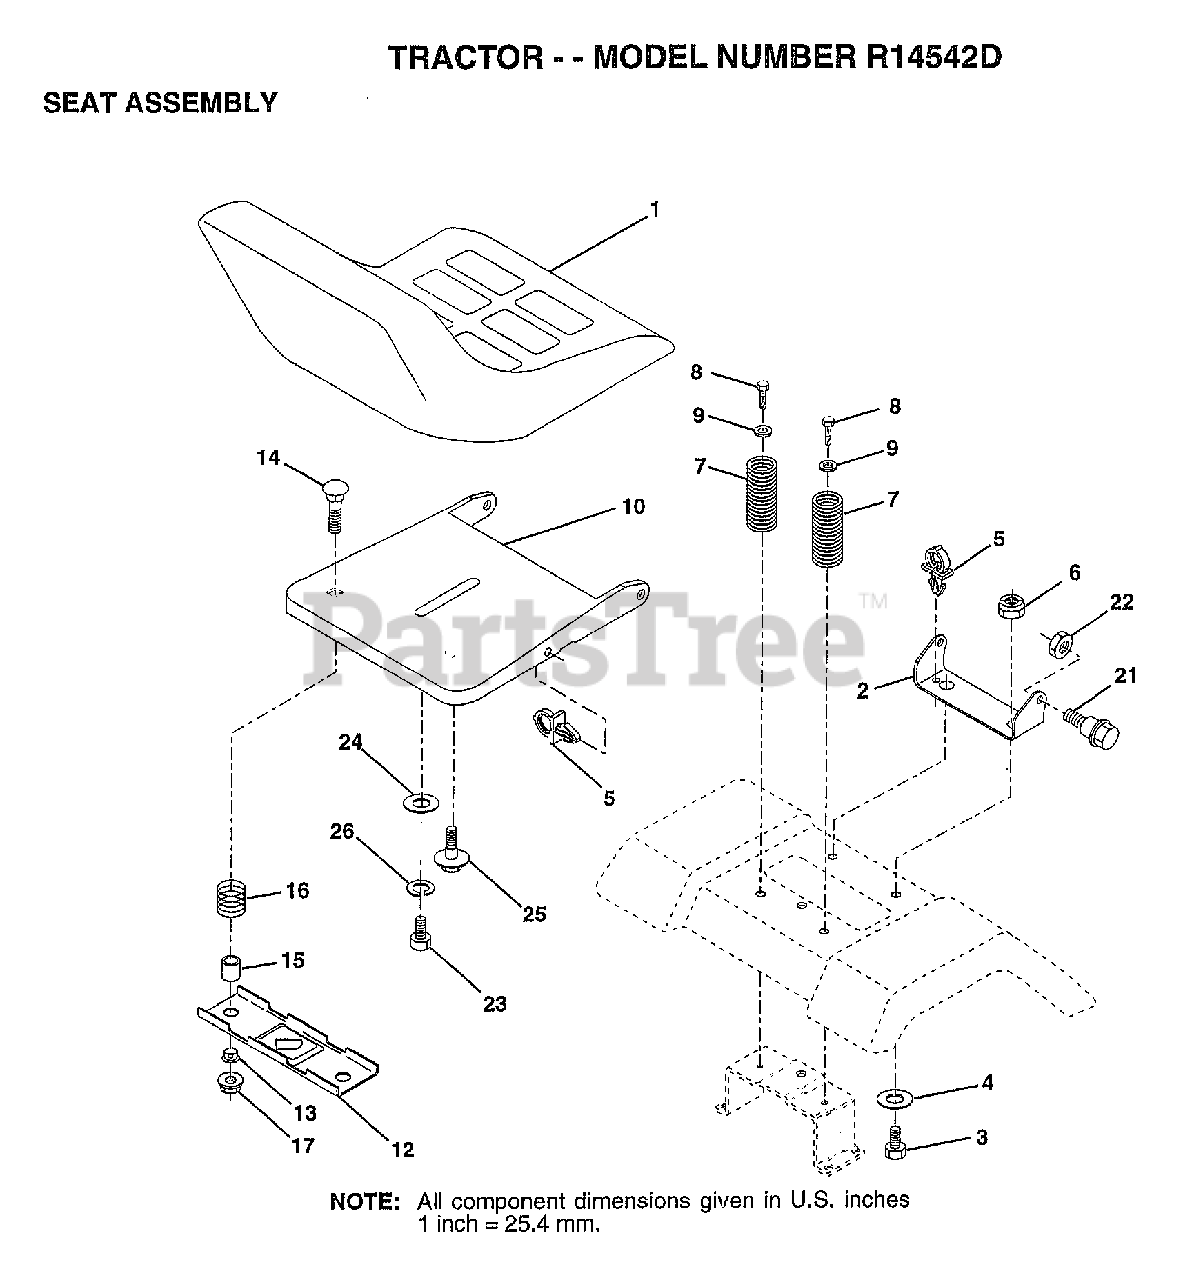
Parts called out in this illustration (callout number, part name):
2	BRACKET PVT SEAT
3	BOLT
4	WASHER PM
5	CLIP.PUSH-IN.HING
6	NUT
7	SPRING COMPRESSIO
8	SCREW GTV
9	WASHER
10	PAN-SEAT
12	BRKT SWITCH
13	BUSHING
14	BOLT-RD HD SQ NK
15	SPLIT SPACER
16	SPRING
21	"BOLT,SHOULDER"
22	NUT
23	BOLT
24	WASHER
25	"BOLT,SHOULDER"
26	LOCKWASHER
